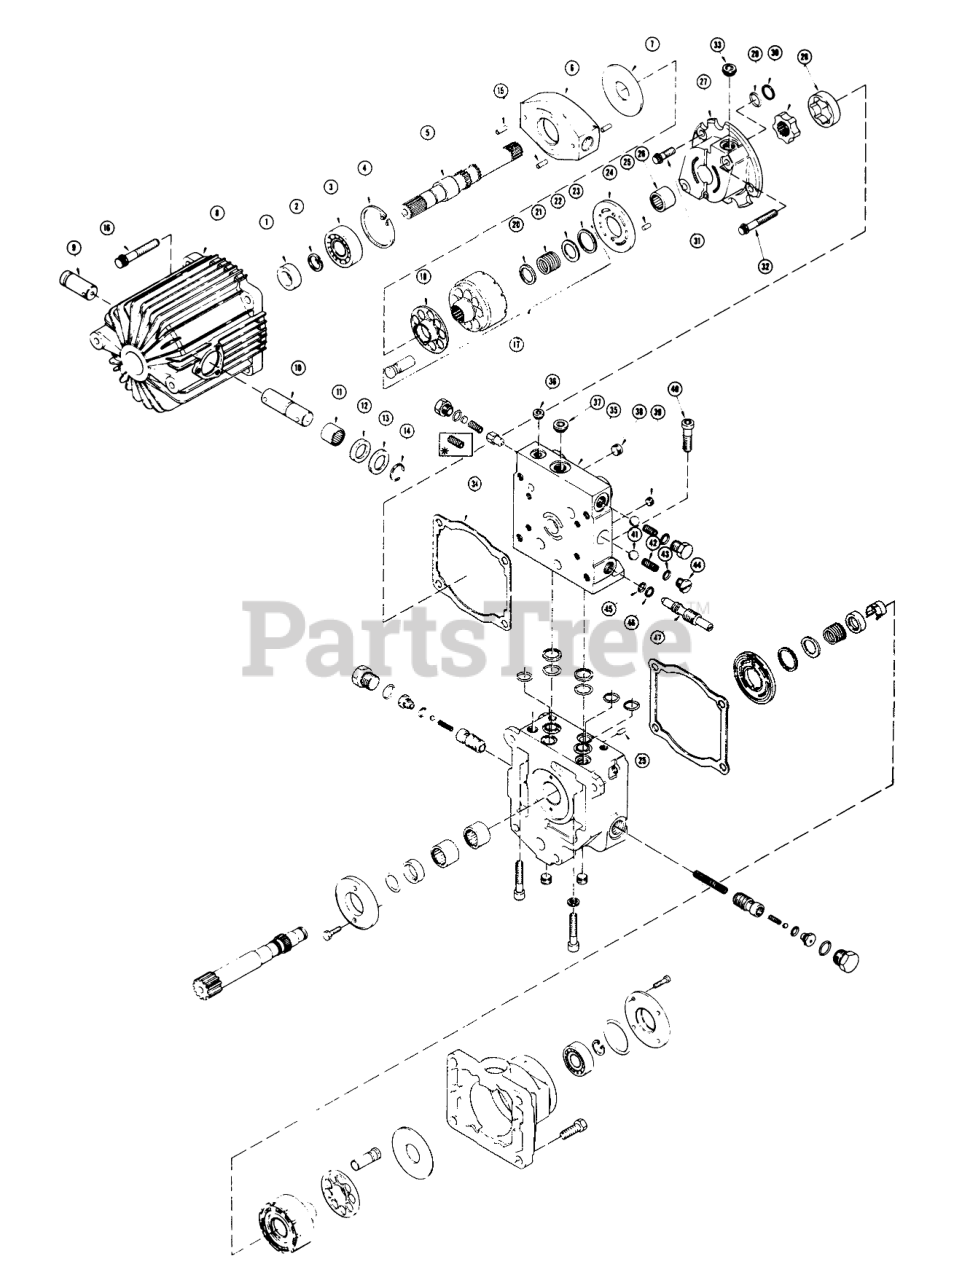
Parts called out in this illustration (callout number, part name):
1	SEAL
2	Snap Ring
3	Ball Bearing
5	Pump Shaft
6	Variable Swash Plate
7	Thrust Plate
8	Pump Housing
9	Stub Trunnion Shaft
10	Trunnion Shaft
11	Needle Bearing
12	SEAL
13	WASHER-LAMBERT
14	RING-LAMBERT
15	Spirol Pin
16	Cap Screw
17	Cylinder Block Kit Inc 18-22
18	RETAINER-SUN 3100194
20	Spacer
21	Spring
22	Front Washer
23	RING-SUN9006250-0112
24	PLATE-VALVE
25	Locating Pin
26	Needle Bearing
27	Charge Pump Housing
28	Assy-Gerotor
29	O RING
30	RING BACKUP
31	Cap Screw Short
32	Cap Screw Long
33	Socket Head Plug
34	Gasket-Pump
35	End Cap-Pump
36	Socket Head Plug
37	Socket Head Plug
38	Pipe Plug
39	Pipe Plug
40	Cap Screw
41	Ball
42	Spring
43	O RING
44	PLUG
45	O-RING
46	Back Up Ring
47	VALVE
